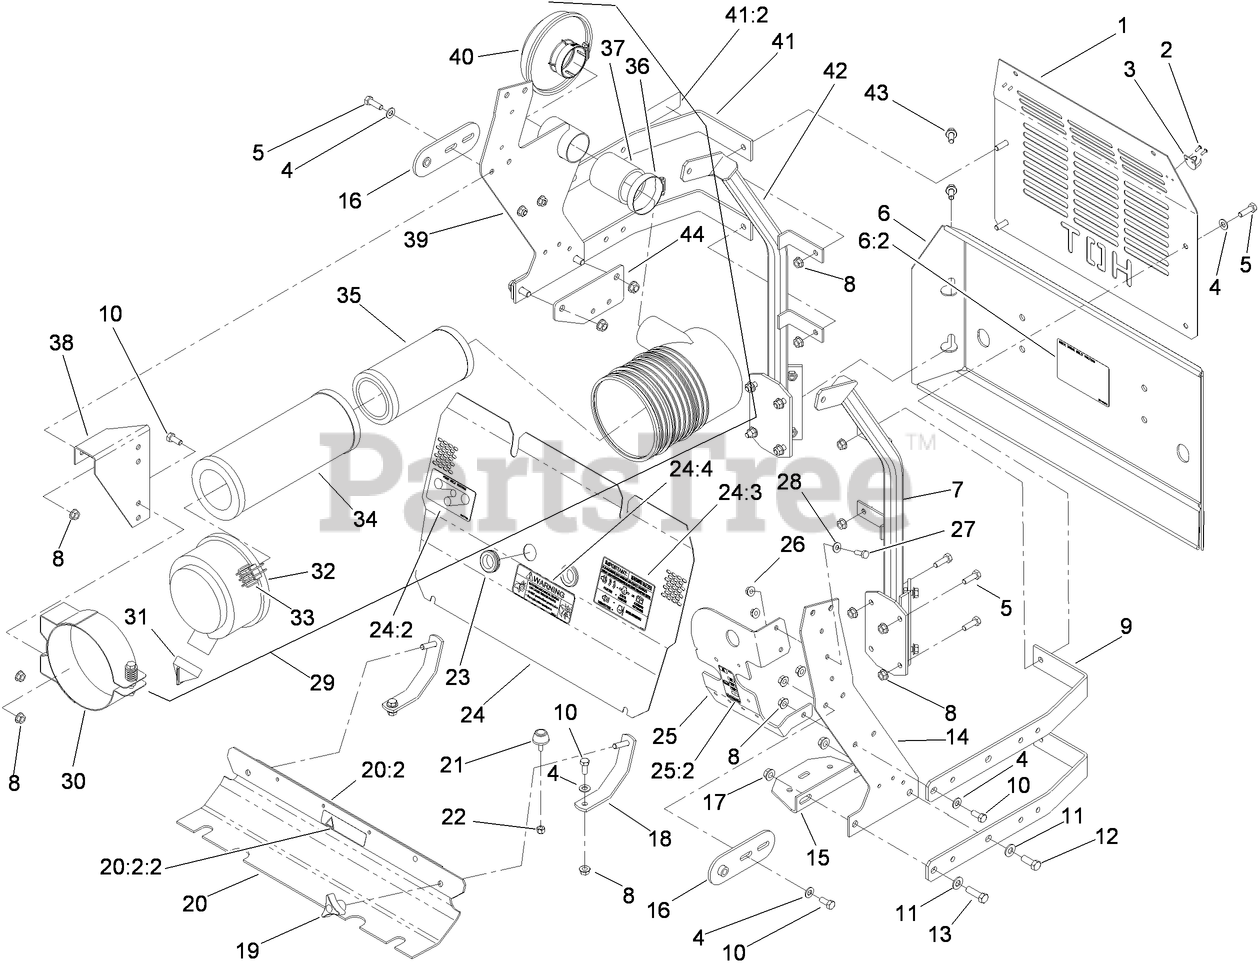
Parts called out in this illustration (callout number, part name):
1	GUARD-MUFFLER
2	RIVET
3	KEEPER-LATCH, RUBBER
4	WASHER-PLAIN
5	SCREW-HH
6	REAR BUMPER ASM
6:2	DECAL-BELT ROUTING, DECK DRIVE
7	FRAME-UPPER, LH REAR
8	NUT-HF
9	BAR-MOUNT FRAME, RADIATOR
10	SCREW-HH
11	WASHER-FLAT
12	SCREW-HH
13	SCREW-HH
14	MOUNT-SIDE, LH
15	BRACKET-BOTTLE
16	SHACKLE-HINGE
17	NUT-HHF, WHIZ
18	MOUNT-BELT SHIELD, ENGINE
19	KNOB-3 PRONG
20	ENGINE BELT SHIELD ASM
20:2	STRIP-SHIELD, BELT
20:2:2	DECAL-COVER, MISSING
21	BUMPER-RUBBER
22	NUT-LOCK, NI
23	GROMMET-RUBBER
24	ENGINE ACCESS PANEL ASM
24:2	DECAL-BELT ROUTING, PUMP
24:3	DECAL-BUZZER, WARNING
24:4	DECAL-DEVICES, ROTATING
25	FUSE/RELAY BRACKET ASM
25:2	DECAL-FUSE
26	NUT-HF
27	SCREW-HH
28	WASHER-FLAT
29	FILTER-AIR
30	BRACKET-FILTER, AIR
31	VALVE-EJECTOR, DUST
32	COVER-FILTER, AIR
33	LATCH-CLEANER, AIR
34	FILTER-AIR
35	FILTER-AIR, SAFETY
36	CLAMP-HOSE
37	HOSE-INTAKE
38	MOUNT-CLEANER, AIR
39	RH RADIATOR AND AC SUPPORT ASM
40	HOOD-CLEANER, 2" AIR INTAKE
41	BAR-RADIATOR
41:2	DECAL-SURFACE, HOT
42	FRAME-UPPER, RH REAR
43	SCREW-HHF
44	PLATE-FUEL FILTER MOUNT
